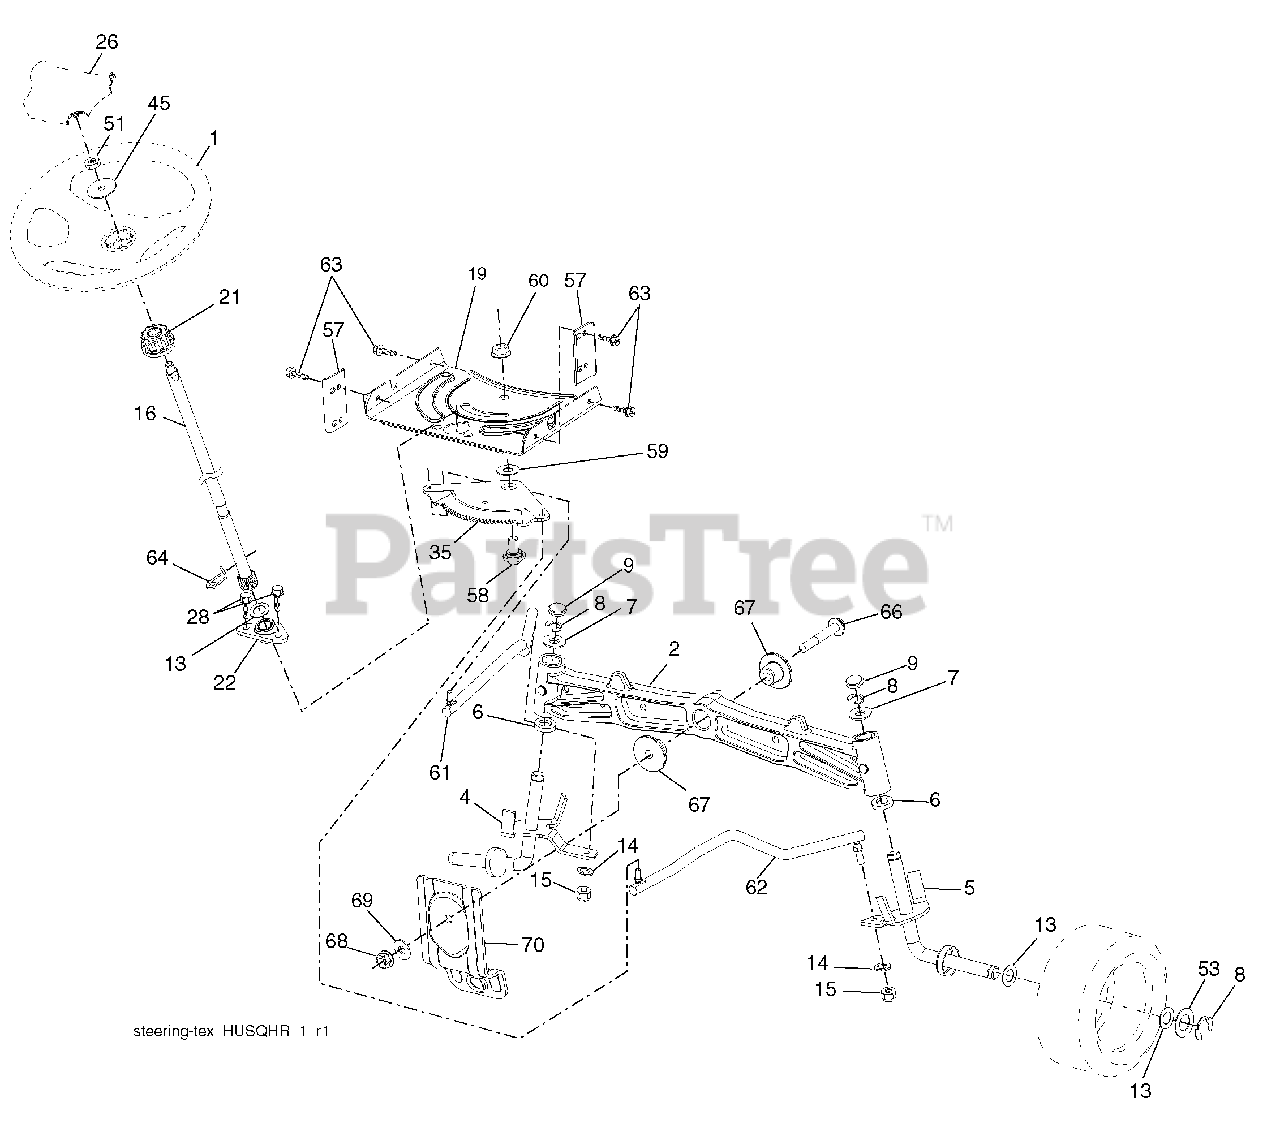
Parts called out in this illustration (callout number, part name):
1	Wheel, Steering
2	Axle Cast Iron
4	Spindle Asm., LH
5	Spindle Asm., RH
6	Washer, Thrust
7	Washer 25/32 x 1-5/8 x 16 Ga.
8	Ring, Klip #T5304-75
9	Cap, Spindle
13	Washer 25/32 x 1-1/4 x 16 Ga.
14	Washer, Lock Hvy Hlcl Spr 3/8
15	Nut, Crown Lock 3/8-24 unf
16	Shaft Steering
19	Plate Steering
21	Adapter, Wheel Steering
22	Steering Support Lower
26	Insert, Wheel Steering
28	Screw 3/8-16 x 3/4
35	Gear, Sector Plate
45	Washer 9/16 ID x 2-3/8 OD 12 Ga.
51	Nut Hex Jam Toplock 1/2-20 unf
53	Washer Hardened .793 x 1.637 x .060
57	Bracket Upstop
58	Bolt Shoulder Sector Pivot CFM
59	Washer Thrust Sector Steering
60	Nut Flange Lock 5/8-11
61	Draglink, LH
62	Draglink, RH
63	Screw 5/16-18 x 3/4
64	Retainer Clip Spring Steering
66	Bolt Hex Fghd 7/16-14 x 3 Serr
67	Bushing PM Front Axle
68	Nut Lock Flange 7/16-14 Gr. 5
69	Washer 1.5 x .505 x .118
70	Bracket Deck Susp. Front
